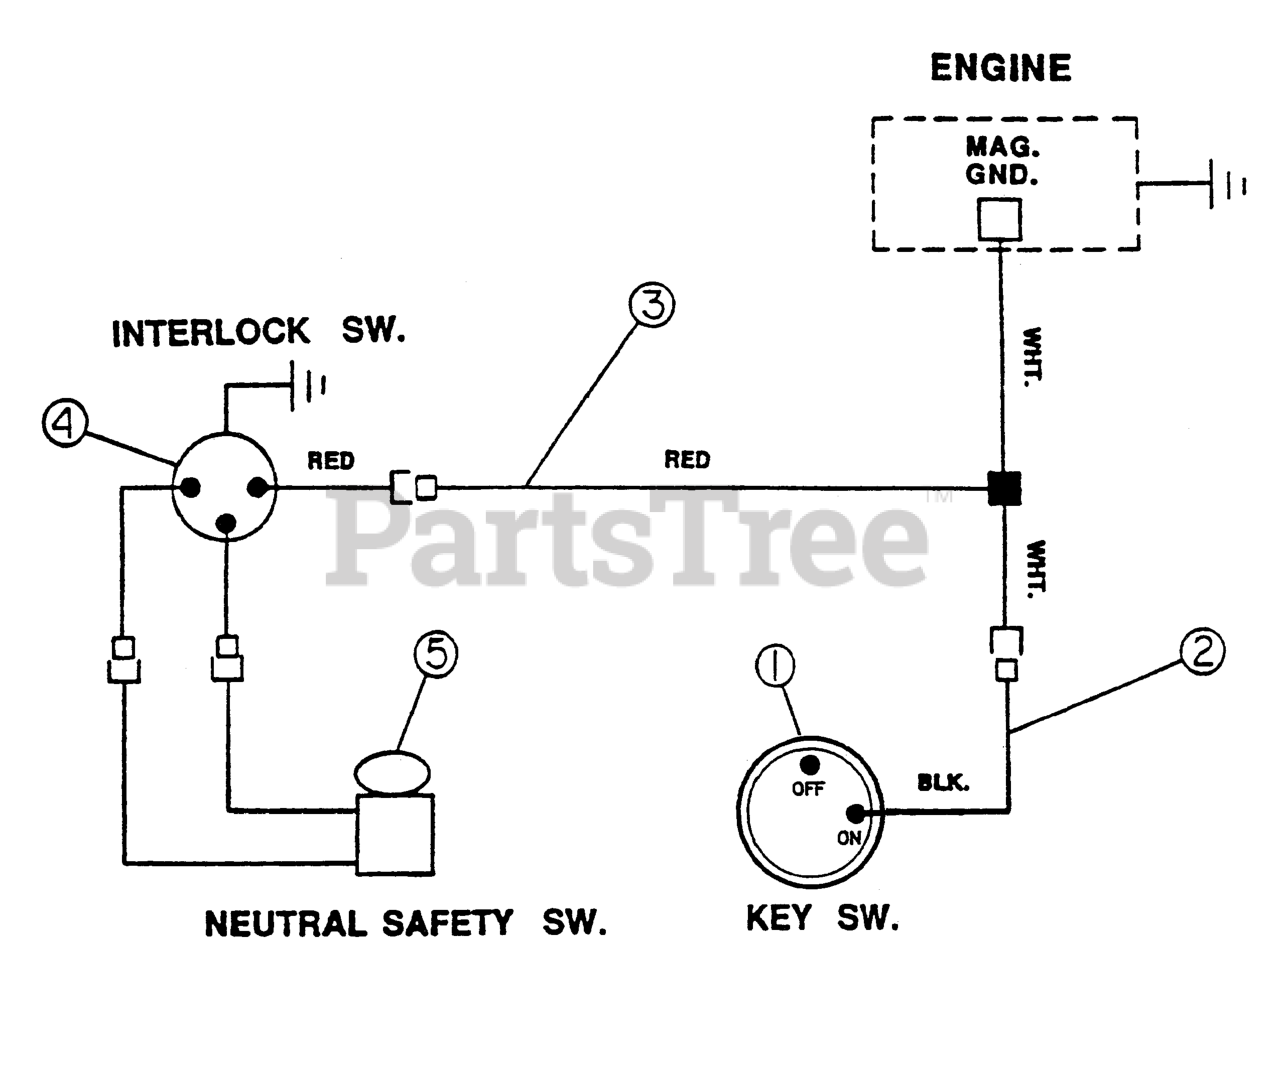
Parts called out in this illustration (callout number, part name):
1	SWITCH, Ignition
2	Pakcard Connector Wire Assembly
3	Engine Wire Assembly
4	Interlock Assembly
5	Safety Switch
5	Switch
